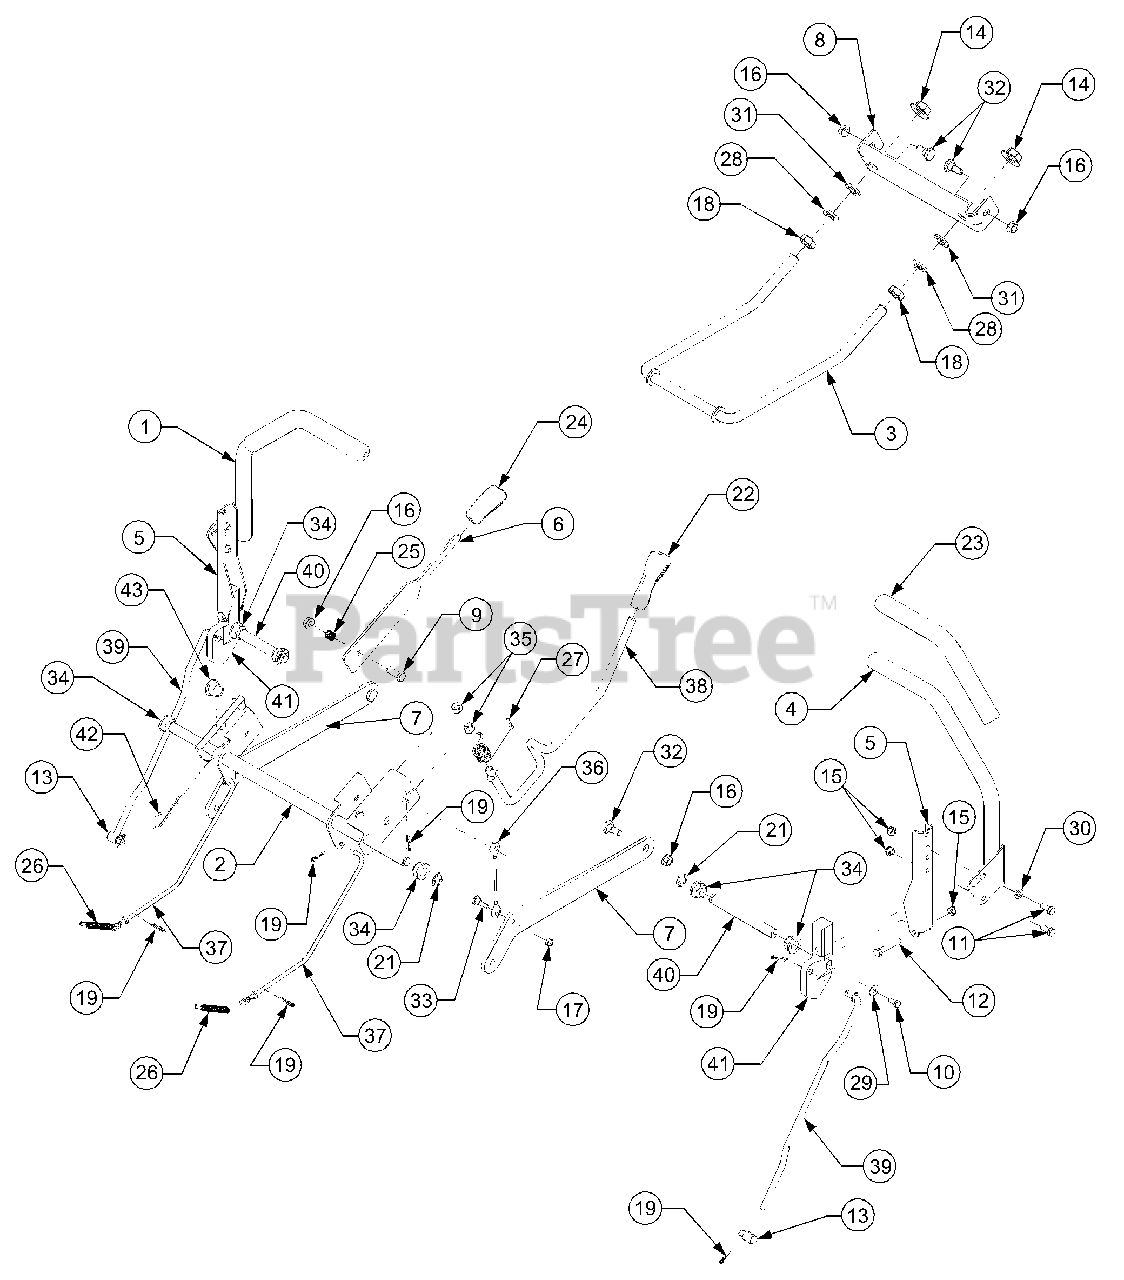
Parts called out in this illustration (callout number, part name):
2	Shaft Assembly, Deck Lift
3	Rod, Deck Front Hanger
10	Screw, Hex Cap, 1/4-20 x .62 GR5
11	Screw, Hex Cap, 5/16-18 x .75 GR5
12	Screw, Hex Cap, 5/16-18 x 1.75 GR5
13	Ferrule, 3/8-24 x .375
14	Nut, Hex Flange, 5/8-18
15	Nut, Hex Insert Lock, 5/16-18 GR5
16	Nut, Hex Flange Lock, 3/8-16 GRF
17	Nut, Hex Insert Lock, 1/4-28 GR2
18	Nut, Hex Jam, 5/8-18 GR5
19	Pin, Internal Cotter
21	E-Ring , .625 Dia. Shaft
22	Grip, Handle
23	Grip, Lapbar
25	Spring, Compression
26	Spring, Extension
27	Spring, Torsion
28	Washer, Lock, 5/8
29	Washer, Bell, .265 x .75 x .062
30	Washer, Flat, .344 x .688 x .065
31	Washer, Flat, .64 x 1.12 x .125
32	Screw, Shoulder, .498 x .340:3/8-16
33	Screw, Shoulder, 1/4-28 x .375
34	Bearing, Hex Flange
35	Bearing, Flange Snap, .50 ID
36	Cable, Deck Lift, 5.05 Long
38	Rod, Deck Lift Handle
39	Rod, Lapbar Control
40	Shaft, Control
42	Pin, Internal Cotter
43	Bearing, Flange, .626 x .938 x .344
